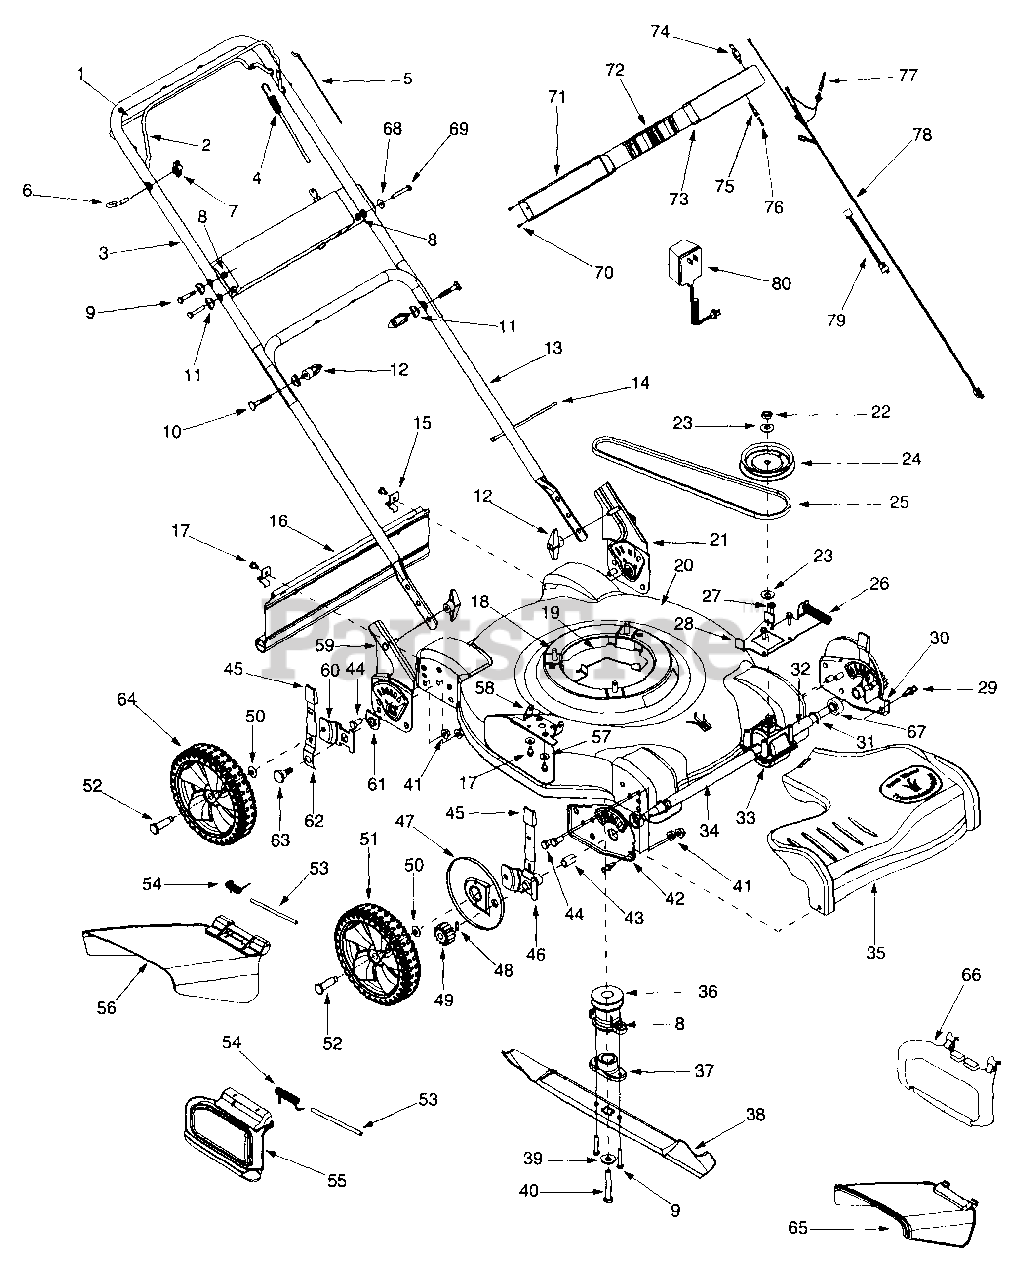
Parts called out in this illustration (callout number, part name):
1	Drive Control Handle
2	Blade Control Handle
4	Drive Control Cable
5	Blade Control Cable
6	Eye Bolt
7	Wing Nut 1/4-20
8	Hex Lock Nut 1/4-20
9	Hex Cap Screw 1/4-20x 1.5
10	Carriage Bolt 5/16-18 x 2.0
11	Shoulder Washer .320 ID x .93 OD
12	Wing Nut 5/16-18
14	Cable Tie
15	Hinge Clip
16	Trail Shield
17	Hex Screw 1/4-14 x .625
18	Hex Washer Screw 3/8-16 x 1.875
19	Engine Belt Keeper Bracket
22	Jam Nut 7/16-20
23	Bell Washer .45 ID x 1.00 OD
24	Pulley
25	V-Belt
26	Compression Spring
27	Hex Washer Screw 1/4-20 x .750
28	Transmission Belt Keeper Bracket
29	Rivet
31	Retainer Ring
32	Sleeve Spacer .550 ID x 2.5
33	Transmission Assembly
34	Sleeve Spacer .550 ID x 8.9
35	Transmission Cover
36	Drive Pulley
37	Blade Adapter
38	Blade 22"
38	Mulching Blade 22"
39	Bell Washer .396 ID x 1.140 OD
40	Hex Cap Screw 3/8-24 x 2.5
41	Lock Nut 3/8-16
43	Sleeve Bearing
44	Hex Cap Screw 3/8-16 x .75
45	Adjustment Knob
46	Spring Lever Assembly
47	Wheel Dust Cover
48	Pin
49	Spur Gear 14T - LH
49	Spur Gear 14T - RH
50	Bell Washer .401 ID x .870 OD
51	Wheel Assembly 8 x 1.8
52	Shoulder Screw 3/8-16
53	Hinge Pin
54	Torsion Spring - Side Discharge
54	Torsion Spring - Mulching Baffle
55	Mulching Baffle (If Equipped)
56	Side Discharge Assembly
57	Bell Washer .265 ID x .75 OD
58	Chute Hinge
61	Height Adjustment Bearing
62	Spring Lever
63	Shoulder Screw 3/8-16
64	Wheel 8 x 1.8
65	Snap Discharge Chute (If Equipped)
66	Snap Mulching Plug (If Equipped)
67	Bearing Spacer
68	Bell Washer .265 ID x .75 OD
69	Hex Cap Screw 1/4-20 x 1.75
70	Screw #12-16 x 1.0
73	Upper Battery Tray
74	Key Switch
75	Fuse Holder
76	Fuse 7.5 Amp
77	Plug
78	Electric Start Harness
79	Harness Extension
80	Battery Charger
